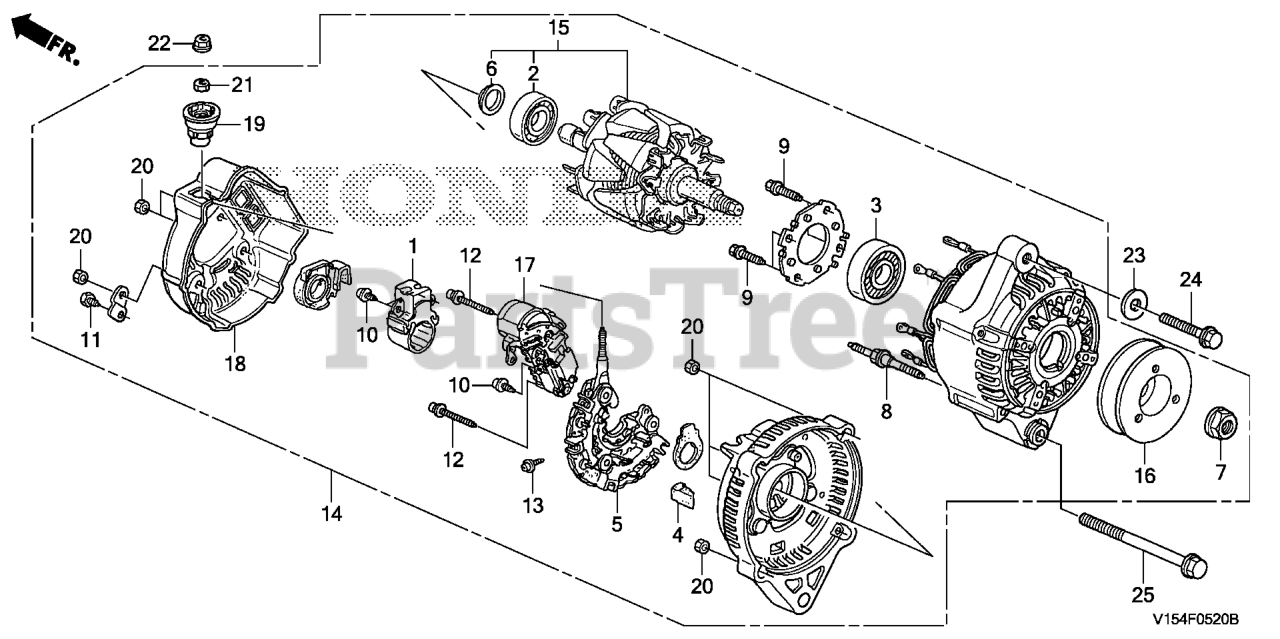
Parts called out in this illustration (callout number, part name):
1	HOLDER ASSY., BRUSH
2	BEARING, RR. GENERATOR
3	BEARING, FR. GENERATOR
4	BUSH, INSULATION
5	RECTIFIER ASSY.
6	COVER, BEARING
7	NUT, PULLEY LOCK
8	BOLT, STUD (6X68)
10	SCREW-WASHER
12	SCREW, WAVE WASHER
13	SCREW, WAVE WASHER
14	ALTERNATOR ASSY. (DENSO)
15	ROTOR ASSY.
17	REGULATOR ASSY.
18	END COVER, RR.
19	BUSH, INSULATION
20	NUT-WASHER (5MM)
21	NUT, HEX. (6MM)
22	NUT-WASHER (6MM)
23	WASHER, PLAIN (8MM)
24	BOLT, FLANGE (8X28)
25	BOLT, FLANGE (10X75)
